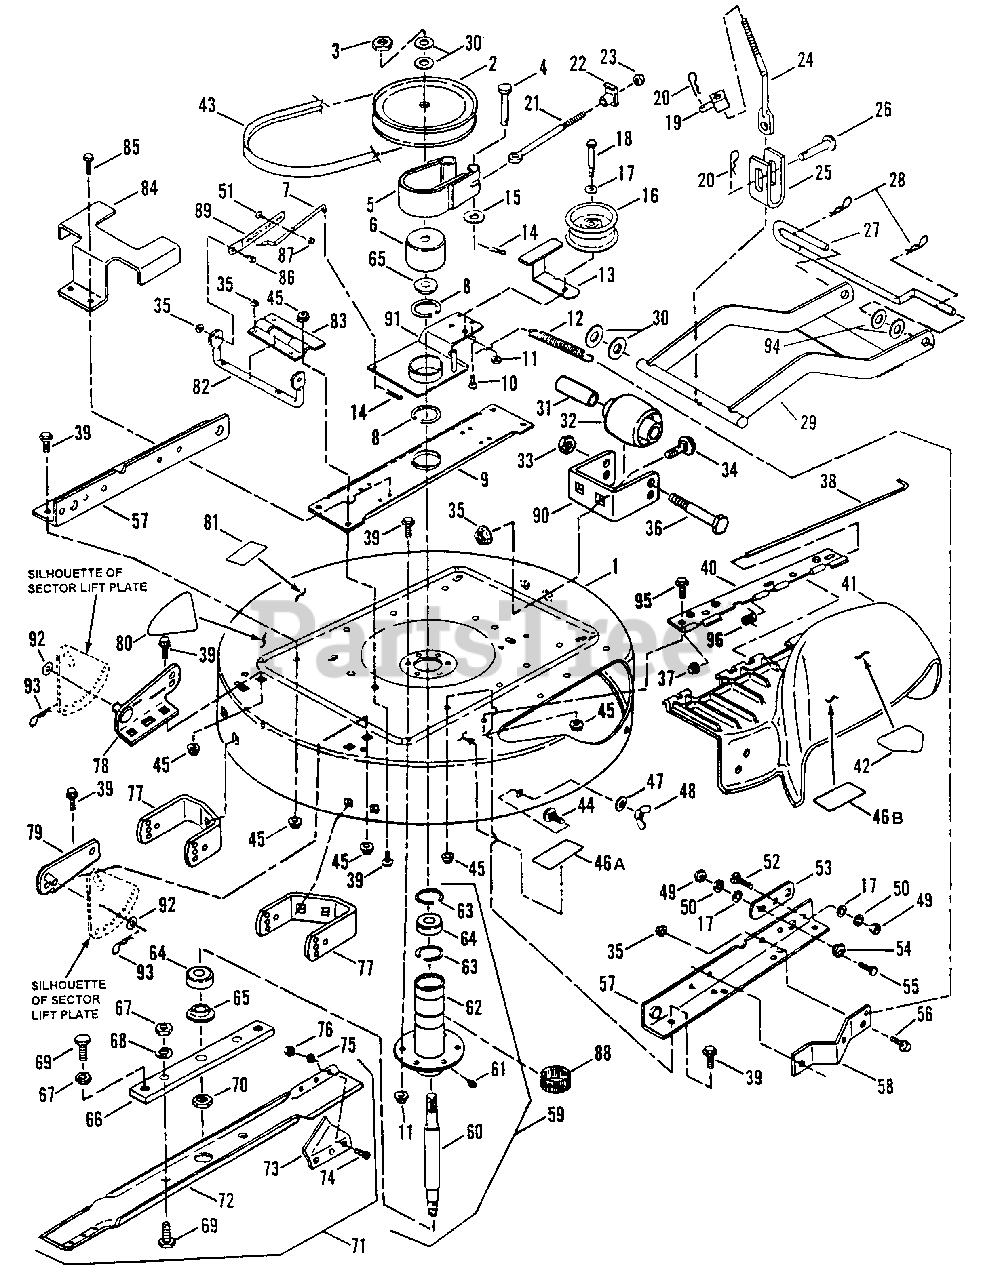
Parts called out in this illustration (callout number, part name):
1	ASSEMBLY, Deck 33" Cutting
2	PULLEY, Spindle, 7" O.D.
3	NUT, 3/4-16 Hex Jam
4	PIN, 1/4 x 1-1/4" Clevis
5	ASSEMBLY, Brake Band
6	DRUM, Brake
7	ROD, Link, Clutch/Brake
8	RING, 2" External Retaining
9	BRACE, Spindle
10	SCREW, 5/16-18 x 3/4" Self-Tapping
11	NUT, 3/8-16 Hex Center Lock, Gr. 5
12	SPRING, Clutch & Brake
13	GUIDE, Belt
14	COTTER-PIN, 3/32 x 3/4"
15	WASHER, 1/4" I.D. x 5/8" O.D. Flat
16	PULLEY, Idler, 4" O.D.
17	WASHER, 3/8 SAE Flat
18	SCREW, 3/8-16 x 1-3/4" Hx. Hd. Cap
19	SWIVEL, Brake
20	PIN, 1/4 x 1-1/8" Hair
21	BOLT, 1/4-20 Eye
22	NUT, 1/4-20 Tee
23	NUT, 1/4-20 Hex, Grade 5
24	ROD, Front Lift
25	BRACKET, Front Lift Hanger
26	PIN, 3/8 x 1-1/2" Clevis
27	PIN, Front Deck Hanger
28	HAIRPIN, for 5/8" Dia.
29	LIFT, Front Arm
30	WASHER, 3/4" I.D. Flat
31	SPACER
32	WHEEL, Gage
33	NUT, 3/8-24 Hex Ctr. Lock, Gr. 5
34	BOLT, 5/16-18 x 1/2" Short Neck Carriage, Grade 5
35	NUT, 5/16-18 Hex Fl. Lock, Gr. 5
36	SCREW, 3/8-24 x 3-3/4" Hex Head Cap, Grade 5
37	PALNUT, 1/4 Hex
38	PIN, Hinge
39	BOLT, 3/8-16 x 3/4" Hex Flange Lock, Grade 5
40	HINGE, Deflector
41	ASSEMBLY, Deflector
41	DEFLECTOR, Discharge
42	DECAL, Danger (Cut Finger)
43	BELT, Drive, 33" Cutting Deck
44	BOLT, 5/16-18 x 3/4" S.N.C., Gr. 5
45	NUT, 3/8-16 Hex Flange Lock
46A	DECAL - CAUTION, Deflector
46B	DECAL - CAUTION, Deflector
47	WASHER, 5/16 Flat
48	NUT, 5/16-18 Wing
49	NUT, 3/8-16 Hex, Grade 5
50	WASHER, 3/8 Split Lock
51	BOLT, 1/4-20 x 1/2" Hex Fl. Lk., Gr 5
52	BOLT, 3/8-16 x 3/4" Carriage, Gr. 5
53	LINK, Adjustment
54	ECCENTRIC, Leveling
55	SCREW, 3/8-16 X 1" H. H. Cap, Gr. 5
56	BOLT, 5/16-18 x 1/2" Hex Flange Lock, Grade 5
57	RAIL, Side
58	ANCHOR, Brake
59	ASSEMBLY, Spindle
60	SPINDLE
61	FITTING, Lube (Press fit for .187 hole-no ball)
62	HOUSING, Spindle
63	RING, Retaining
64	BEARING, Spindle
65	WASHER, Spindle
66	HOLDER, Blade
67	NUT, 1/2-20 Hex Jam
68	WASHER, 1/2 Int. Tooth Lock
69	SCREW, 1/2-20 x 1-1/4" Hex Head Cap, Grade 5
70	NUT, 5/8-18 Hex Lock, Gr. B or 5
71	ASSEMBLY, Blade & Air Lift
72	BLADE, 33" Cutting Deck Euro
73	AIR-LIFT
74	SCREW, 5/16-24 x 11/16" Machine
75	WASHER, 5/16 int. Tooth Lock
76	NUT, 5/16-24 Hex, Grade 5
77	BRACKET, Gage Wheel (Rear)
78	BRACKET, Rear Deck Lift, Left Side
79	BRACKET, Rear Deck Lift, Right Side
80	DECAL, 33" Hi-Vac
81	DECAL - CAUTION (Rotating Blades)
82	ARM, Pivot
83	BRACKET, Pivot Arm
84	GUIDE, Belt
85	SCREW, 5/16-18 x 5/8" Self-Tap.
86	SCREW, 5/16-18 x 3/4" Shoulder
87	NUT, 1/4-20 Hex Flange Lock, Gr. 5
88	RING, Tolerance
89	BRACKET, Link, Clutch/Brake
90	BRACKET, Gage Wheel (Front)
91	ARM, Idler
92	WASHER, 3/8" Flat
93	HAIRPIN, for 3/8" Dia
94	WASHER, 1/2" I.D. Flat
95	BOLT, 3/8-16 x 3/4" Hex Flange Lock, Grade 5
96	SPRING, Hinge
